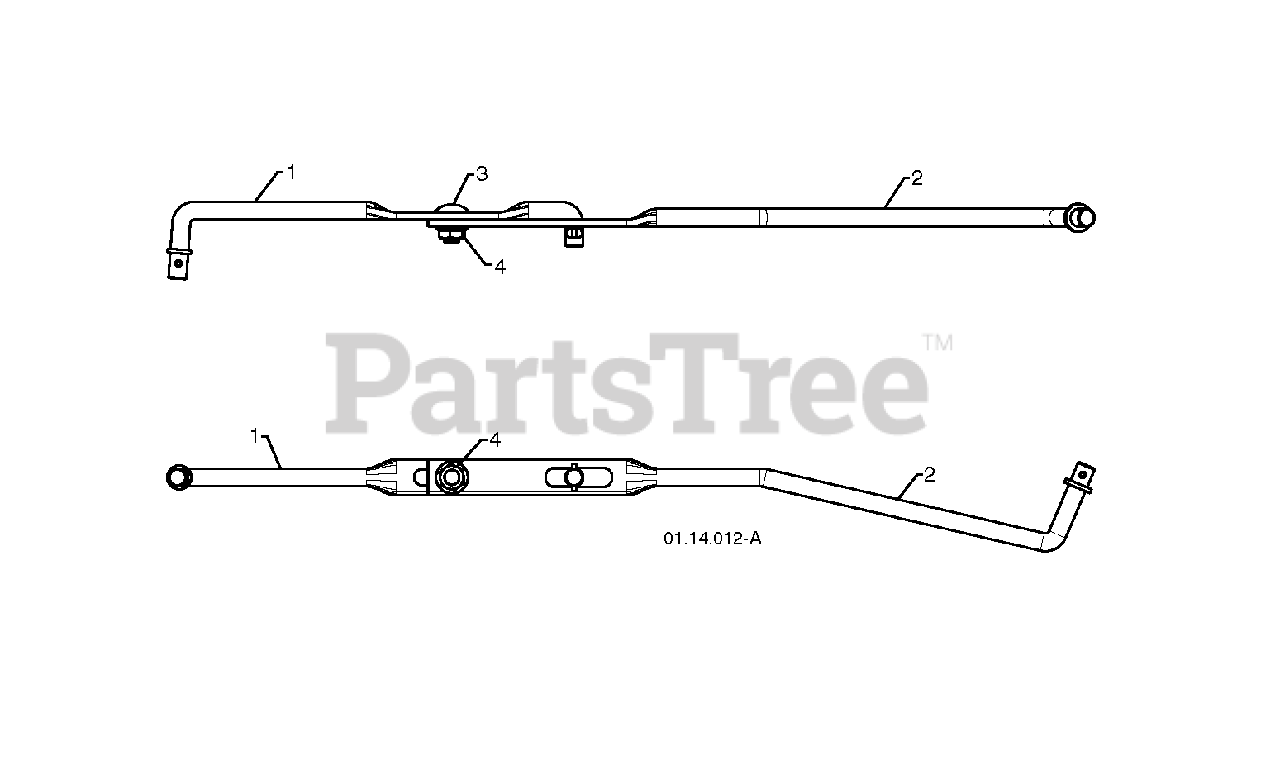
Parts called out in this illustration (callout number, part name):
1	ROD, UPPER SPEED CONTROL
2	ROD, LOWER SPEED CONTROL
3	BOLT
4	NUT.FLANGE.5/16
